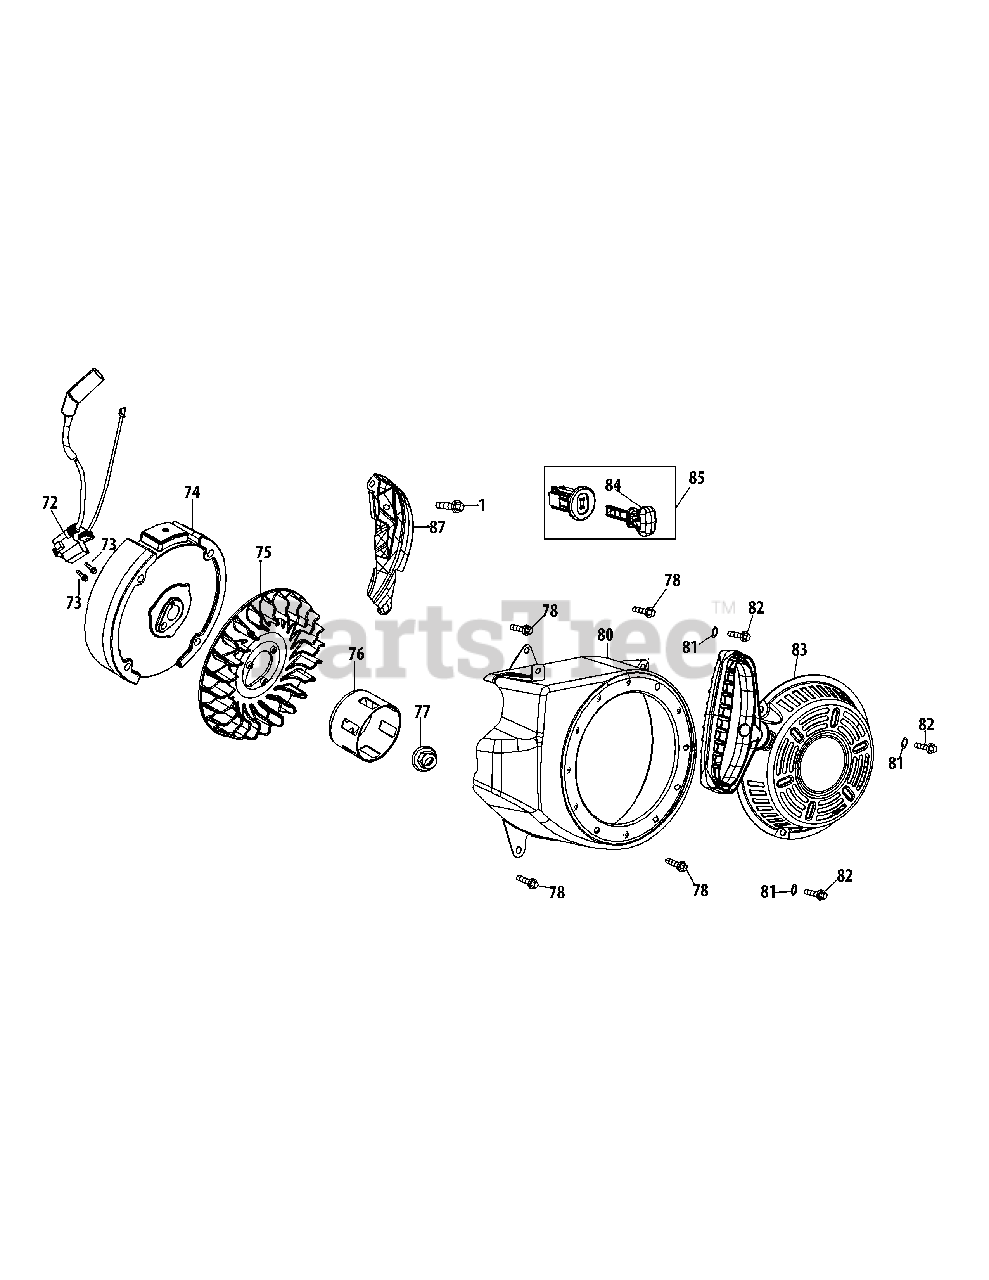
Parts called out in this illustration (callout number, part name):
1	Bolt m6×16
72	Ignition Module
73	Bolt M6×25
74	Flywheel
75	Cooling Fan
76	Starter Cup
77	Flywheel Nut, M14×1.5
78	Bolt m6×14
80	Blower Housing
81	Gasket 6
82	Bolt M6×10
83	Starter, Recoil
84	Key
85	Key Switch Base
87	Flywheel Baffle
